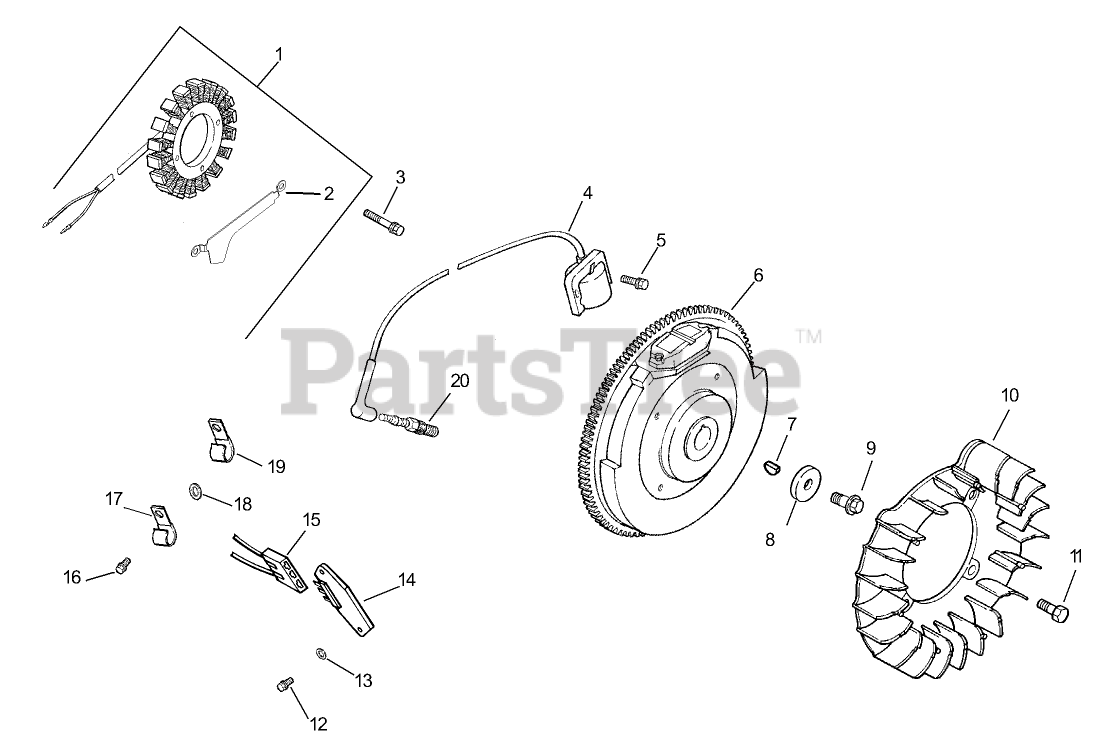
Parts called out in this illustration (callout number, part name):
1	15 Amp Stator Kit (Includes 2)
2	Bracket-Wire, Stator
3	SCREW-THREAD FORMING (M5X0.8X25)
4	Module-Ignition
5	SCREW-FLANGE, THREAD FORMING (M5X.8X20)
6	Flywheel
7	KEY (3/16 X 5/8)
8	WASHER-FLAT (13/32)
9	SCREW-FLANGE (M10X1.5X45)
10	Fan
11	BOLT-SHOULDER (M6x1.0x16)
12	SCREW-PHL HD (11-16X.88)
13	WASHER-FLAT (.188)
14	Rectifier-Regulator, 15 amp
15	Connector (3 contact)
16	Screw-WSH HD Tap (8-18X.50)
17	CLIP-CABLE
18	WASHER-FLAT (1/4)
19	Clip-Cable
20	Spark Plug
